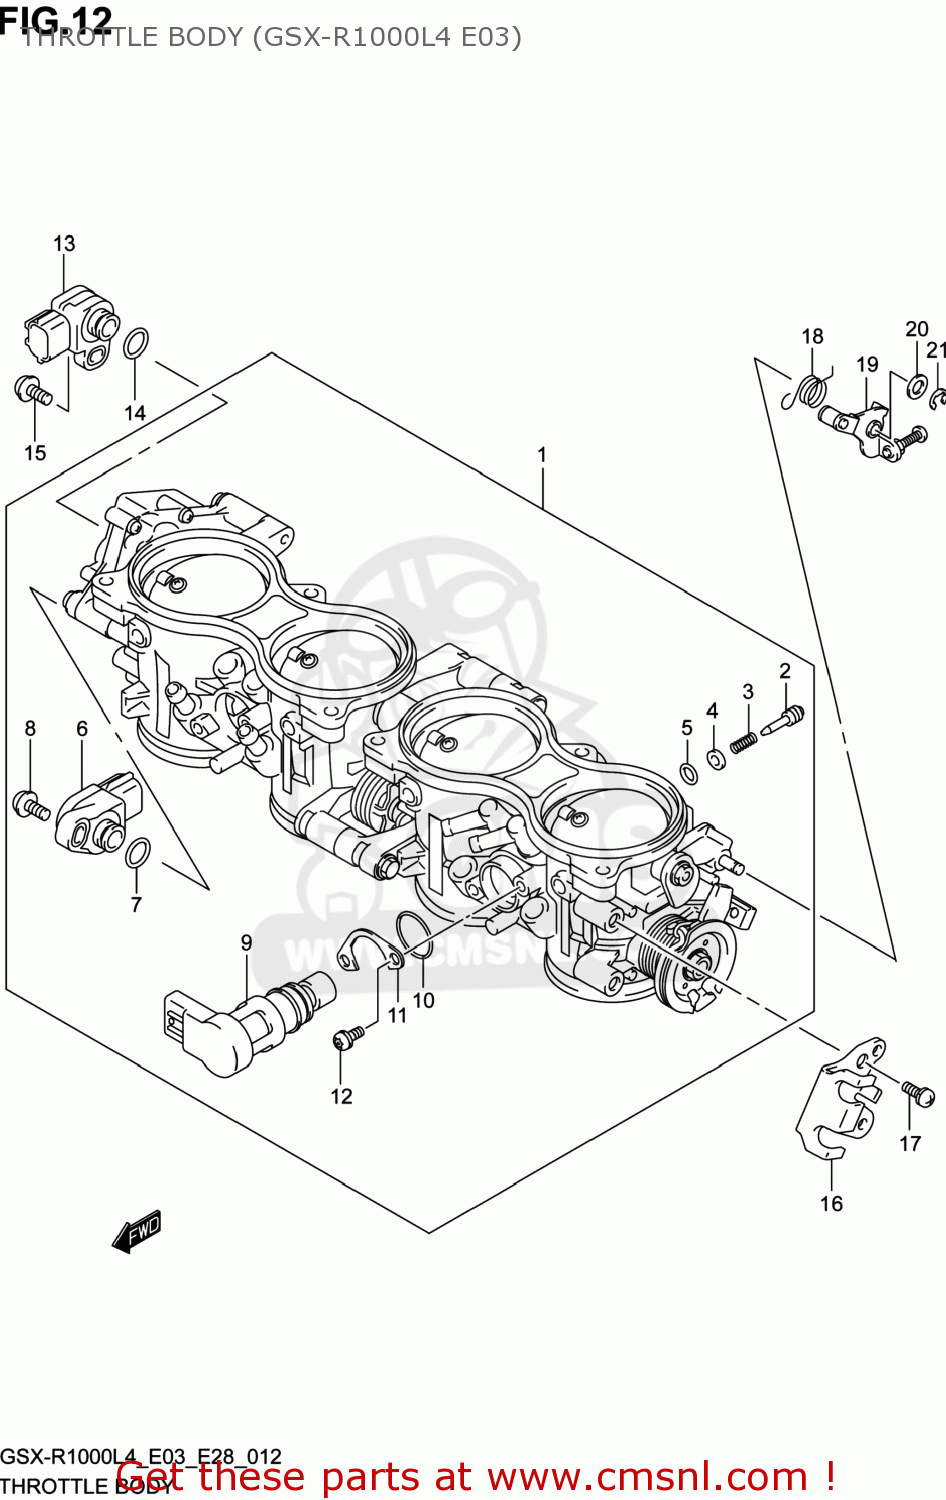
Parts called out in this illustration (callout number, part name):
1	BODY ASSY,THROTTLE
2	SCREW,AIR ADJUST
3	SPRING
4	WASHER
5	O RING
6	SENSOR ASSY,THROTTLE MAIN
7	O RING
8	SCREW
9	VALVE ASSY,ISC
10	O RING
11	PLATE,ISC VALVE
12	SCREW
13	SENSOR ASSY,THROTTLE SUB
14	O RING
15	SCREW
16	PLATE,STAY
17	SCREW
18	SPRING
19	LEVER ASSY,LINK
20	WASHER
21	E CLIP
